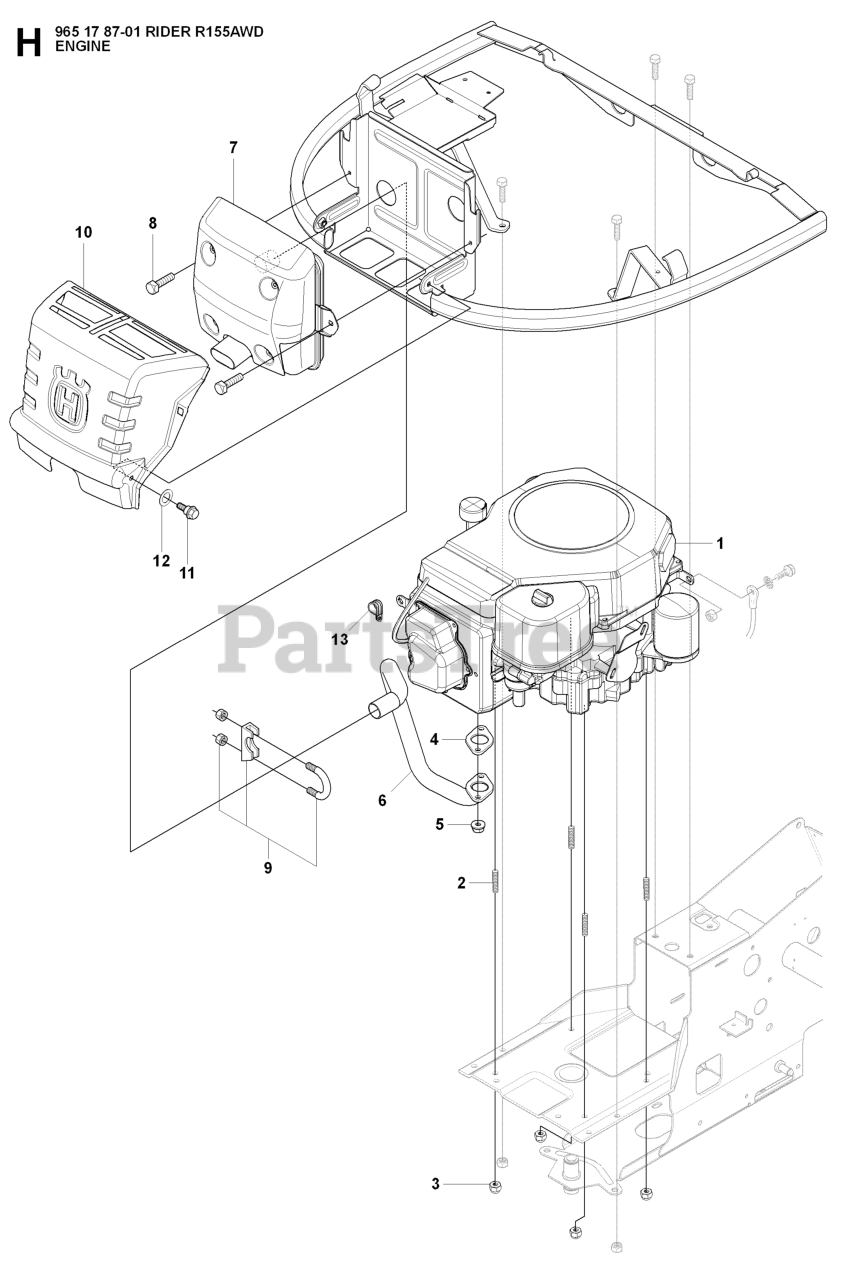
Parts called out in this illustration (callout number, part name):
3	LOCKNUT M8
4	EXHAUST GASKET
6	EXHAUST PIPE ASSY
7	MUFFLER ASSY
9	CLAMP
10	HEAT PROTECTOR
12	SPRINGWASHER
